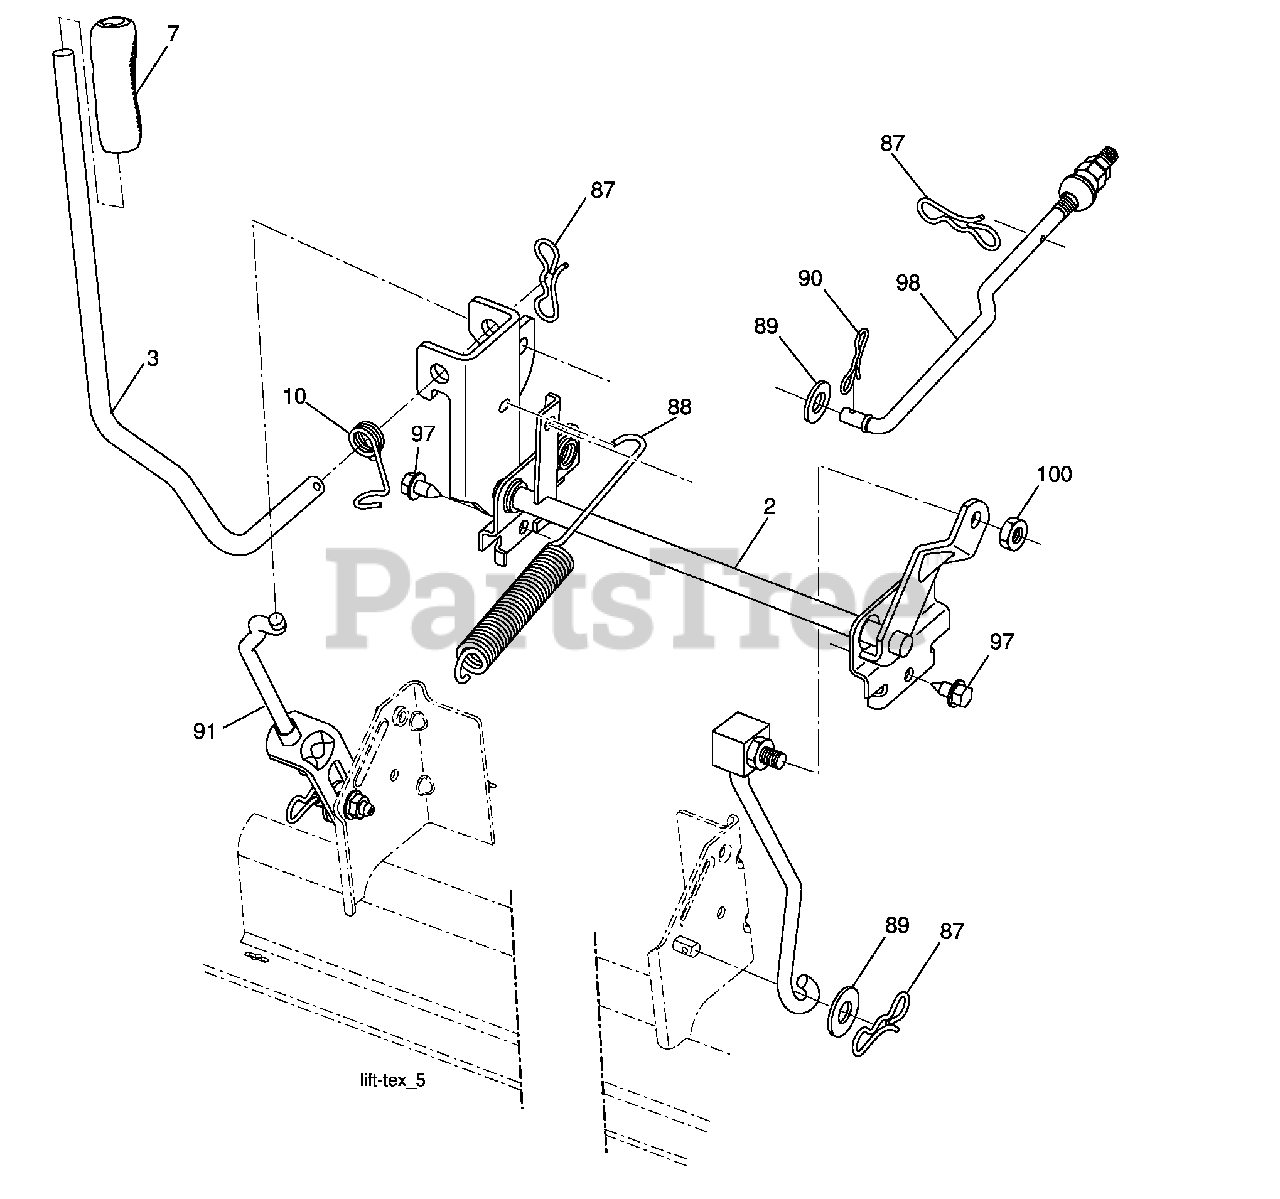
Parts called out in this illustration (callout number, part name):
2	Shaft Asm., Lift
3	Lever Asm., Lift
7	Grip, Lever
10	Spring Torsion
87	Pin Cotter 7/16 Bow Tie Lock
88	Spring Lift Assist
89	Washer Clear Zinc
90	Pin Cotter 5/16 Bow Tie Lock
91	Link Lift Susp Mower Rear
97	Screw 3/8-16 x .75 Smgml Tap/R.Z
98	Link Lift Susp. Front Mower
100	Nut Centerlock 3/8-16 UNC
